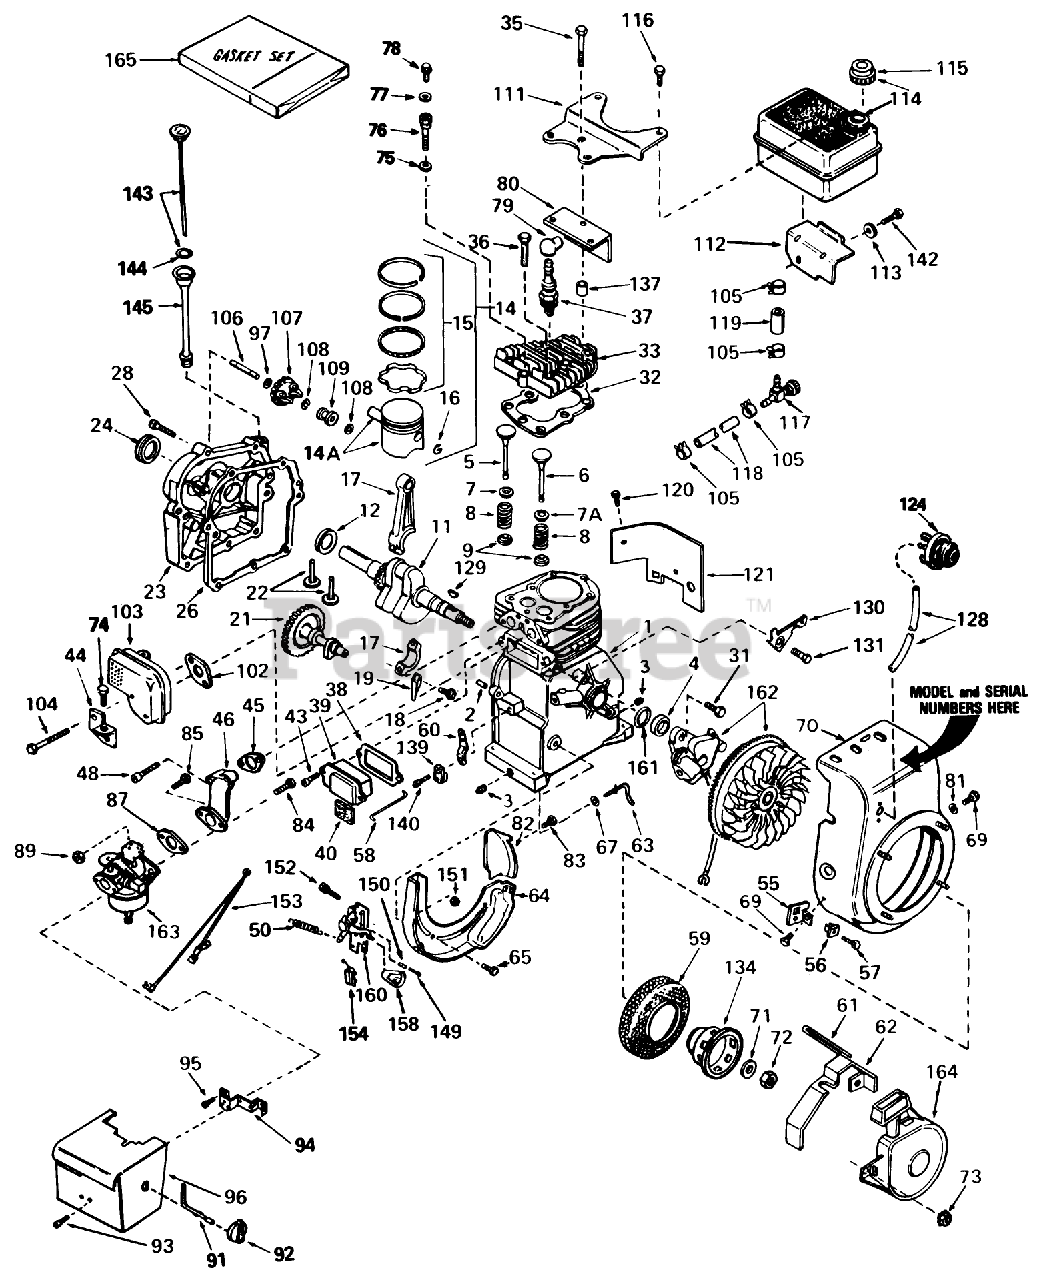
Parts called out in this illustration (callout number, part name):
1	Cylinder Assy. (Incl. Nos.2, 34)
2	Pin-Dowel
3	Plug-Drain, Oil (SQH 1/4-18)
4	Seal-Oil
5	Valve-Intake Standard (Incl. Ref. #151)
5	Valve-Intake 1/32" oversize (Incl. Ref. #151)
6	Valve, Exhaust (Std.)(Incl. No. 40)
6	Valve, Intake (1/32" oversize)(Incl. No. 40)
7	Cap-Upper Valve Spring
7A	Cap, Upper Valve Spg (Exhaust)
8	Spring-Valve
9	Cap-Valve, Spring
11	Crankshaft ASM
12	Washer-Thrust
14	Piston, Pin Ring Assy., (Incl. Ref. #15 16) (Std.)
14	Piston, Pin Ring Assy., (Incl. Ref. #15 16) (.010 Oversize)
14	Piston, Pin Ring Assy., (Incl. Ref. #15 16) (.020 Oversize)
14A	Piston Pin Assy. (Incl. Ref. #16) (Std.)
14A	Piston Pin Assy., (Incl. Ref. #16) (.010 Oversize)
14A	Piston Pin Assy. (Incl. Ref. #16) (.020 Oversize)
15	Ring Set-Piston Std.
15	Ring Set-Piston .010 oversize
15	Ring Set-Piston .020 oversize
16	Ring-Retaining, Piston Pin
17	Rod Assy., Connecting (Incl. Nos. 18 19)
18	Bolt-Rod, Connecting
19	Dipper-Oil
21	Camshaft
22	Lifter-Valve
23	Cover, Cylinder (Incl. Ref. #24 106)
24	Seal-Oil
26	Gasket-Cylinder Cover
28	Screw (1/4-20 x 1-1/4)
31	Screw
32	Oil Fill Tube
33	Head Cylinder
35	Screw (5/16-18 X 2)
36	Screw (5/16-18x1-1/2)
37	Plug, Spark (J17LM or equiv.)
37	Plug, Spark (Champion RCJ-8)
38	Gasket Breather
39	Breather Assembly (Incl. Nos. 52 84)
40	Element-Breather
43	Screw
44	Bracket-Cover, Carburetor
45	Gasket-Intake
46	Pipe-Intake
48	Screw (1/4-20 x 1-19/32)
50	Spring-Extension
55	Bracket
56	Grommet
57	Screw
58	Link-Governor to Throttle
59	Screen-Starter
60	Lever-Governor
61	Seal, Snowguard
62	Guard-Starter
63	Rod-Governor
64	Baffle-Blower Housing
65	Screw (1/4-20x19/32)
67	Washer-Flat
69	Screw
70	Housing-Blower
71	Washer-Belleville
72	Nut-Flywheel
73	Nut and Lock Washer (1/4-28)
74	Screw (10-24 x 3/8)
75	Washer-Flat
76	Screw ( 5/16-18 x 1-1/2)
77	Washer
78	Screw
79	Cover-Spark Plug
80	Baffle-Heat
81	Washer
82	Baffle-Extension
83	Screw-Hex Washer Hd.
85	Screw-Fil. Hd.
87	Gasket
89	Nut and Lock Washer (1/4-28)
91	Rod-Choke
92	Knob-Control
93	Screw (8-32 X 5/16)
94	Bracket-Choke
95	Screw (10-32 x 1/2)
96	Cover, Carburetor
97	Washer-Flat
102	Gasket-Exhaust
103	Muffler
104	Screw-Fil. Hd.
105	Clamp-Line, Fuel
106	Shaft-Governor
107	Governor Gear ASM
108	Ring-Retaining
109	Spool-Governor
111	Plate-Fuel Tank
112	Bracket-Fuel Tank
113	Washer
114	481-1261 SENATOR TI
115	Cap, Fuel
116	Screw (1/4-15x7/8)
117	Valve-Shut Off
118	Line-Fuel
119	Line-Fuel (8.62)
120	Screw
121	Extension-Blower
124	Primer Assy.
128	Line, Primer
129	Key-Flywheel
130	Bracket-Hold Down
131	Screw (10-24 x 9/16)
134	Cup, Starter
137	pacer
139	Clamp-Lever, Governor
140	Screw
142	Screw Assembly
143	Dipstick
144	O-Ring
145	Tube Fill
149	Screw
150	Spring-Compression
151	Nut-Lock
152	Screw
153	Wire-Ground
154	Terminal
158	Knob-Control
160	Control Assembly, Speed (Incl. Ref. #155 thru 158 160)
161	Gasket Stator
162	Magneto (The complete magneto in not available as an assembly. The magneto number is shown for reference purposes only. Order component parts individually, as shown in parts list)
163	Carburetor (Incl. Ref. #87)
164	Starter Assy., Rewind
165	Gasket Set
